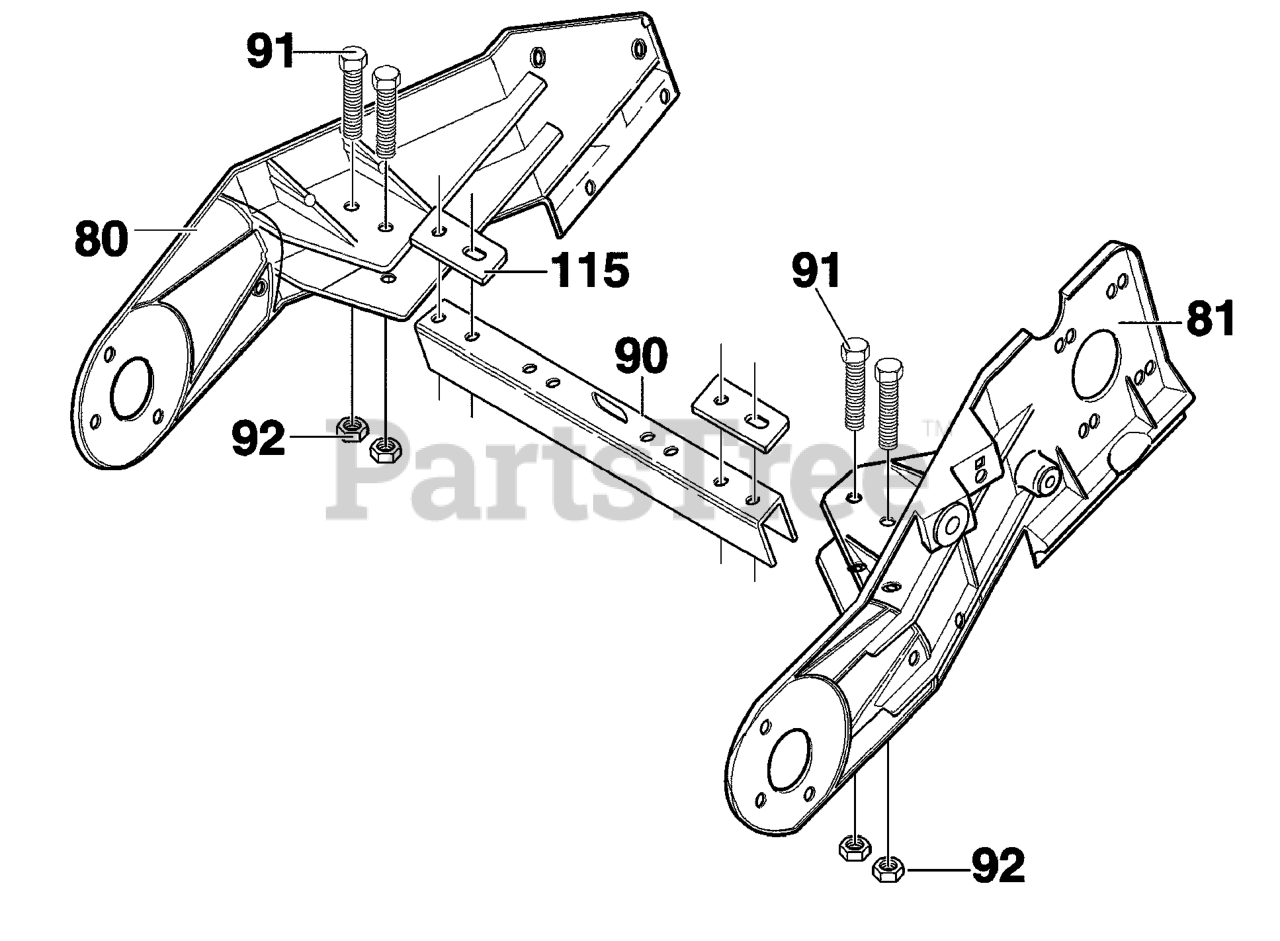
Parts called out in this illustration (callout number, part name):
80	FRAME, SIDE RH
81	FRAME, SIDE LH
90	CHANNEL SUPPORT
91	SCREW, 1/4-20 x 2.00
92	NUT, 1/4-20
115	PLATE, BOLTING SUPPORT
